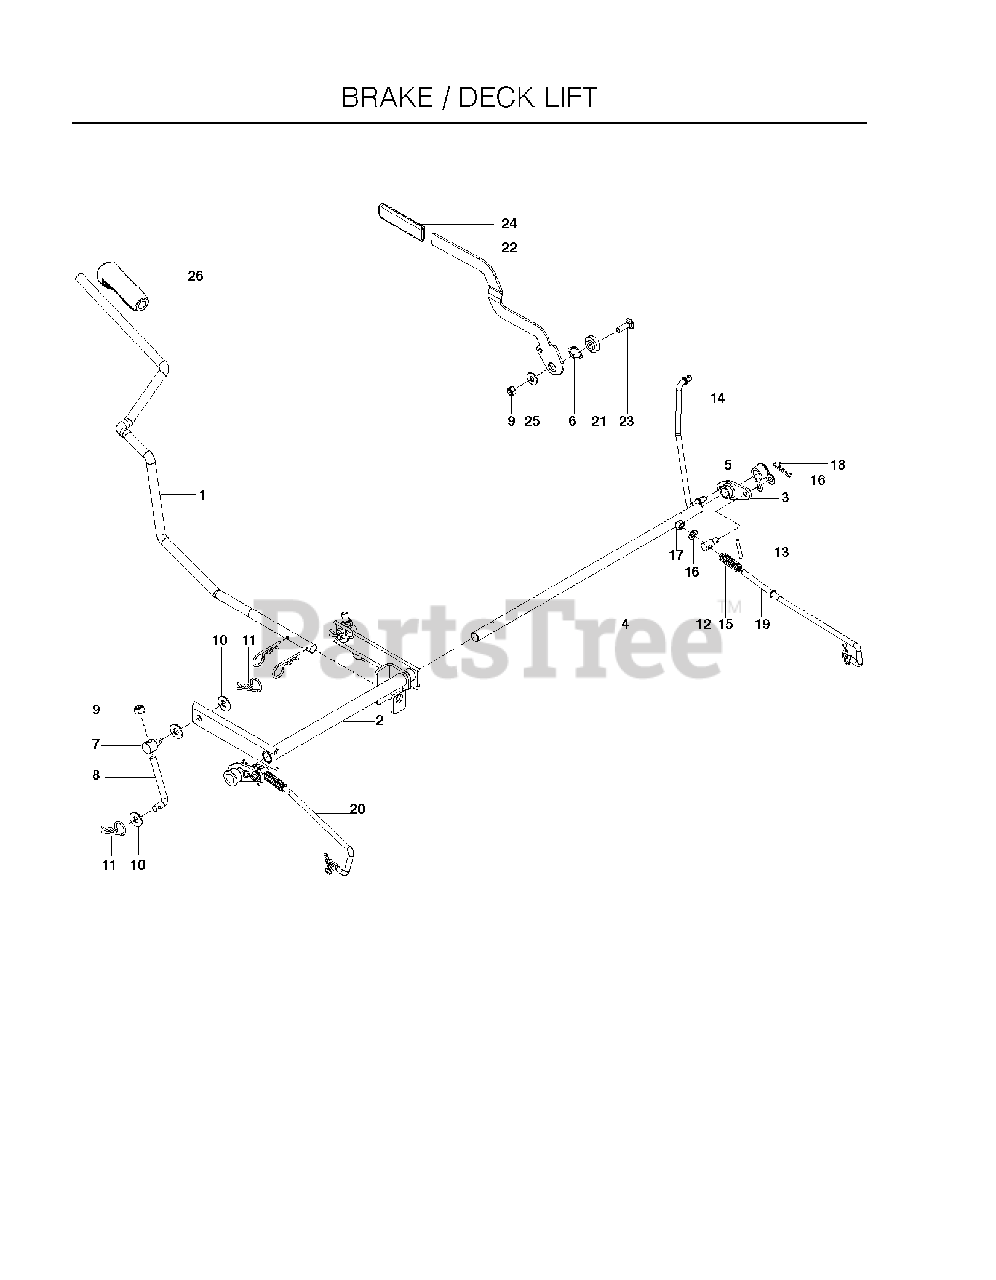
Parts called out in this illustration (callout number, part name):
1	ARM, LIFT HANDLE, BLK
2	WLDMT.LIFT.SHAFT.BLACK
3	BELLCRANK, BRAKE
4	ROD, BRAKE
5	PLASTIC BUSHING
6	WASHER, .825 X 1.087, WAVE
8	L-ROD 3.5
9	NUT 3/8-16 NYLOC
10	WASHER 3/8 FLAT
11	HAIRPIN #4
12	BRAKE SWIVEL
13	ROLL PIN 3/16 X 1-1/4 ZD
14	LINKAGE, BRAKE, UPPER
16	FLAT WASHER 5/16 SAE
17	NUT 5/16 NYLOC
18	HAIRPIN #2
19	LINKAGE, EZT BRAKE RT
20	LINKAGE, EZT BRAKE LT
21	BRAKE ARM PIVOT
22	HANDLE, BRAKE, BLK
23	RHSNB 3/8-16 X 1-1/4
24	GRIP BRAKE HANDLE
25	WASHER, 7/16 DISC SPRING
26	GRIP.LEVER.5625.ID
